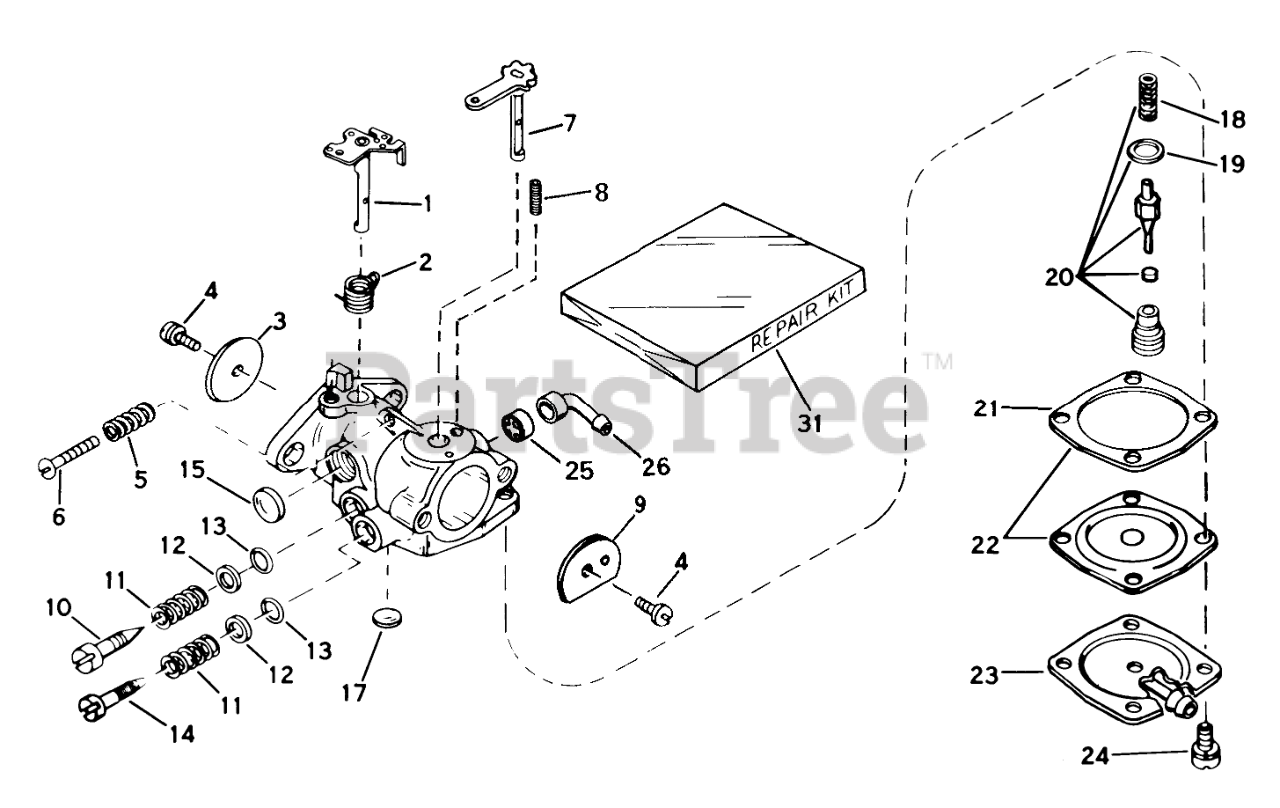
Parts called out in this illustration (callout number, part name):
1	Shaft & Lever Assy., Throttle
2	Spring Return
3	Shutter-Throttle
4	Screw-Shutter
5	Spring-Tension
6	Screw-Throttle Crack Screw / Idle Speed
7	Shaft & Lever Assy., Choke
8	Spring-Positioning, Choke
9	Shutter-Choke
10	Screw-Idle Adjustment
13	"O"Ring
14	Screw Main Adjustment
15	Plug-Welch, Idle Mixture Well
17	Plug Welch
18	Spring-Valve
19	Gasket-Valve Seat
20	Inlet Needle, Seat, Spring & Gasket Assy. (Incl. Nos. 18 & 19)
21	Gasket-Diaphragm
22	Diaphragm Assy. (Incl. No. 21)
23	Cover, Diaphragm
24	Screw, Diaphragm Cover
25	Valve Check
26	Fitting-Inlet, Fuel
31	Kit-Repair
